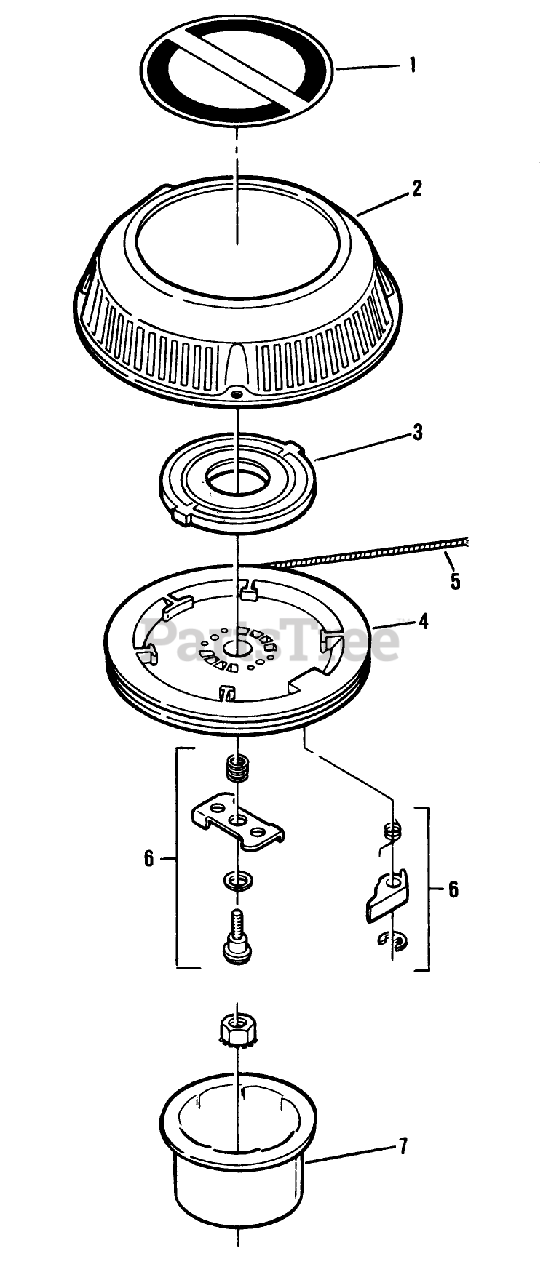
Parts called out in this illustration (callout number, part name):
1	Decal
4	LOCKNUT S
6	DOG KIT AY.
7	HUB STARTER SM
